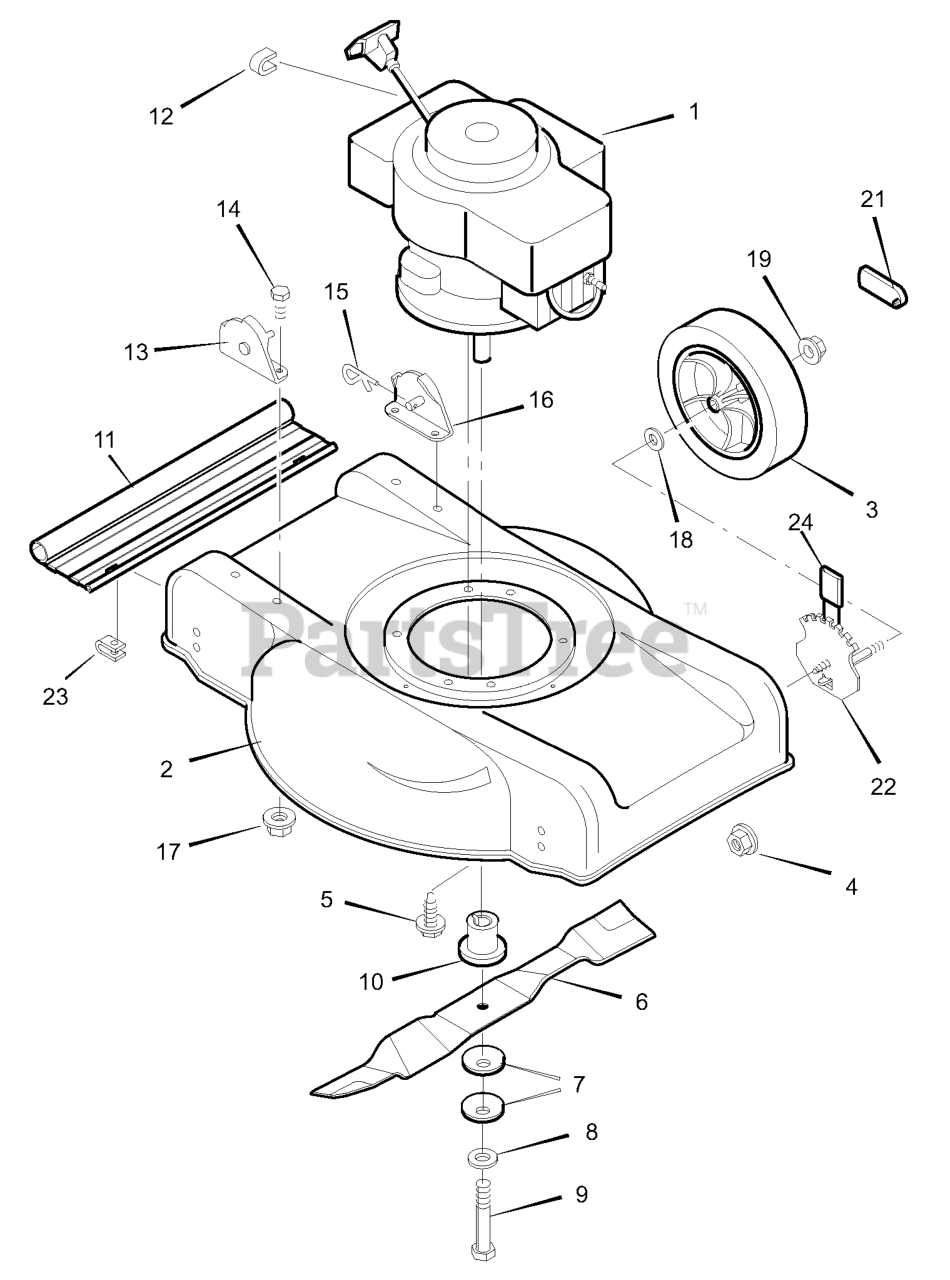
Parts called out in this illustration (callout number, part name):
2	Housing, For Folding Handle
3	8X2.00 WHL BARBB D-GR
4	NUT.38-16 FLANGELOCK
5	SCREW, TRI .38-16 X
6	SINGLE BLADE
7	WASHER.39-2.2 11G FL
8	WASHER.40.81 16G FLT
9	BOLT-HEX.37-24X1.50 P
10	BLADE ADAPTER MULCH
11	Deflector, Rear
12	CLAMP-ROPE STOP
13	Bracket, Right Handle
14	BOLT,HEX .25 20X0.62
15	PIN-HAIR .38D-.062T
16	Bracket, Left Handle
17	NUT,FLANGELOCK.25-20
18	WASHER,SPRING .52X.99
19	NUT, CENTERLOCK .38-
20	HUB CAP-SM. BLK. PLA
21	HUBCAP 8X2 BARBB GRAY
22	HGT ADJ 20/21/22 STD
23	GUARD, RETAINER REAR
24	GRIP-VINYL-75X1.25
